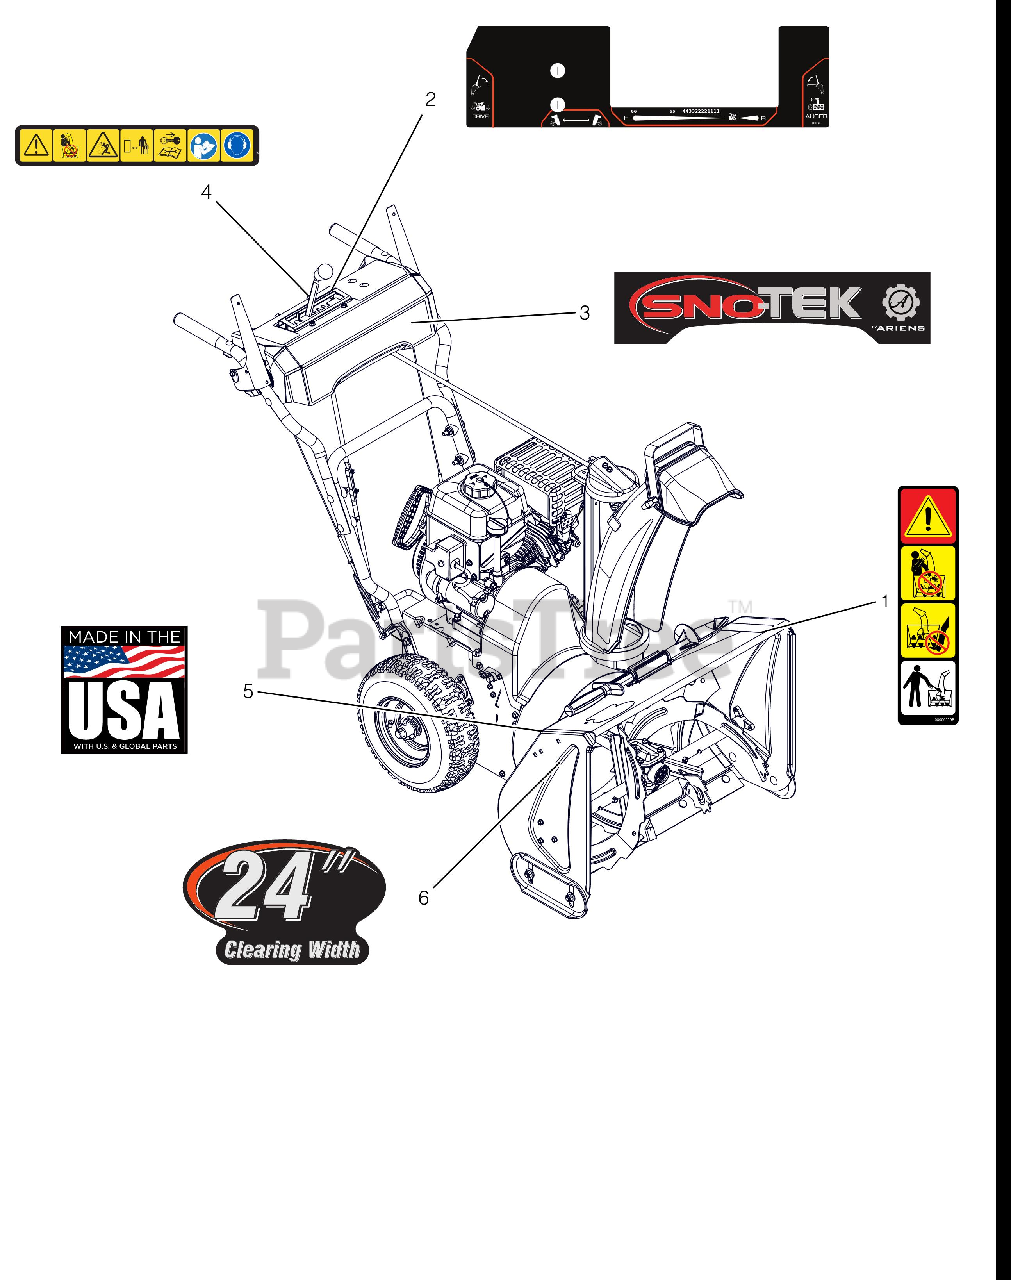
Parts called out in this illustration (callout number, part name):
1	DECAL, DANGER - ROTATING PARTS
2	DECAL,CONTROL-COMP MAN
3	DECAL, DASH, SNO-TEK
4	DECAL,DASH - SAFETY
5	DECAL, MADE IN USA
6	DECAL, HOUSING SNO-TEK 24
